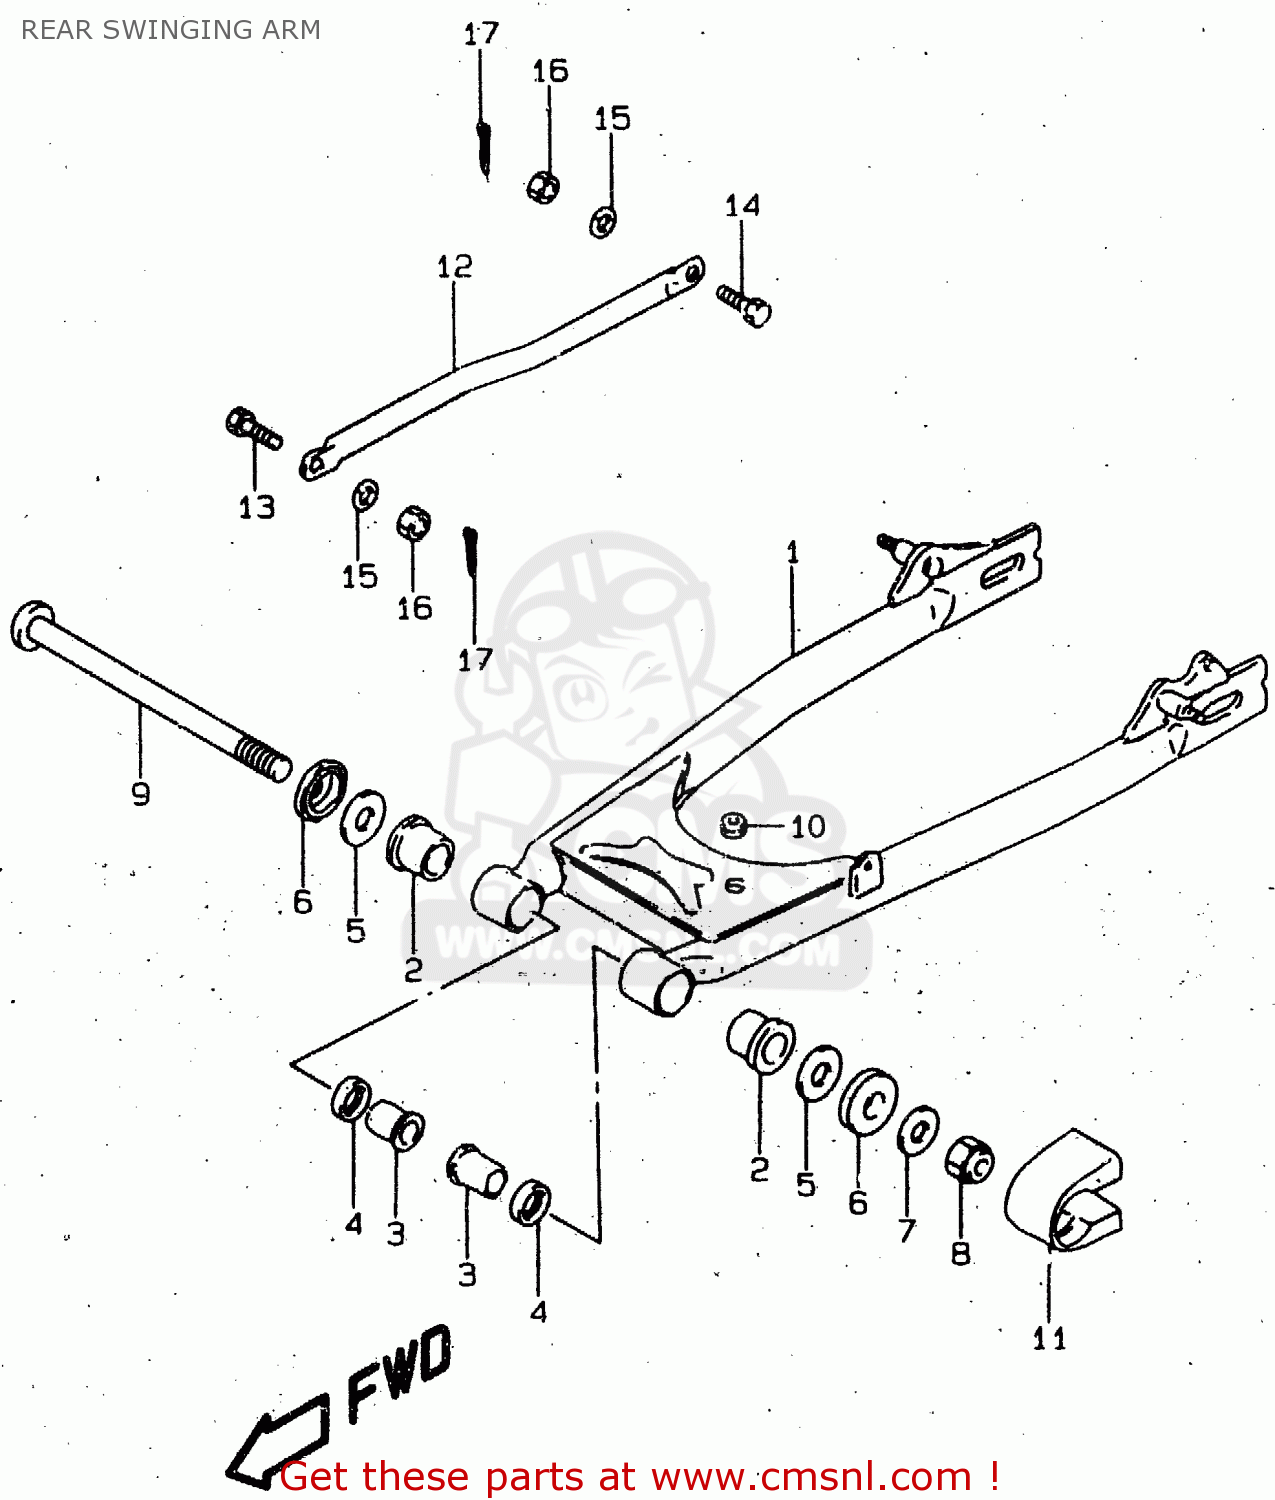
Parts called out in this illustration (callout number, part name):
1	SWINGINGARM ASSY,RR
2	BUSH,RR SWINGING ARM PIVOT
3	SPACER,RR SWGARM PIVOT
4	SEAL,OIL(20X27X5)
5	WASHER
6	CVR,RR SWGARM DUST SEAL(OD:40)
7	WASHER
8	NUT 14MM
9	SHAFT,RR SWINGINGARM PIVOT
10	CUSHION
11	BUFFER,CHAIN TOUCH DEFENSE
12	LINK,RR TORQUE
13	BOLT(8X22.5)
14	BOLT(8X26.5)
15	WASHER,LOCK
16	NUT
17	PIN 20X20
